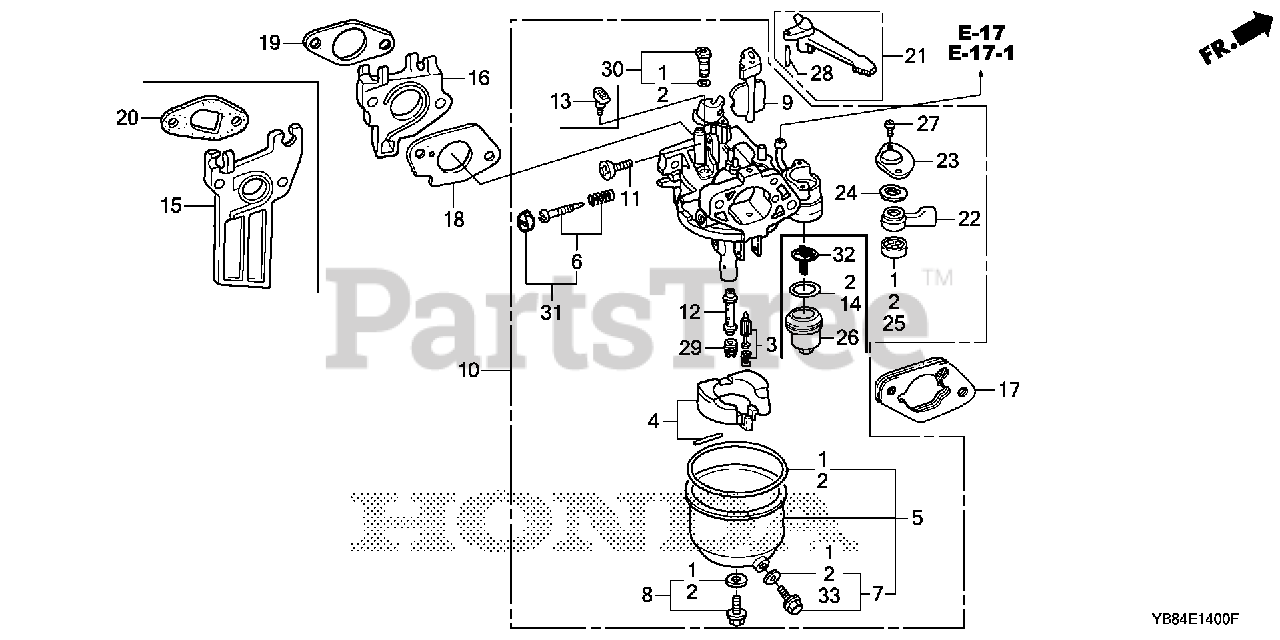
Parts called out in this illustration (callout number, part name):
1	GASKET SET (CARBURETOR NO.)
3	VALVE SET, FLOAT (CARBURETOR NO.) (SEAT NOT INCLUDED)
4	FLOAT SET
5	CHAMBER SET, FLOAT
7	SCREW SET, DRAIN
8	SCREW SET (CARBURETOR NO.)
9	CHOKE SET
10	CARBURETOR ASSY. (BE61V A)
11	SCREW, THROTTLE STOP
12	NOZZLE, MAIN (CARBURETOR NO.)
15	INSULATOR, CARBURETOR
17	SPACER, CARBURETOR
18	GASKET, CARBURETOR
20	GASKET, INSULATOR
21	LEVER, CHOKE (STD)
22	LEVER, VALVE
23	PLATE, LEVER SETTING (CARBURETOR NO.)
24	SPRING, PETCOCK LEVER (CARBURETOR NO.)
25	GASKET, VALVE
27	SCREW, PAN (3X6)
28	PIN, SPRING (2X12)
29	JET, MAIN (#65)
29	JET, MAIN (#60)
29	JET, MAIN (#62)
30	JET SET, PILOT (#40) (ADVENTURE GREEN) (CARBURETOR NO.)
33	WASHER, PLAIN (6.2X10.7 DRAIN) (CARBURETOR NO.)
